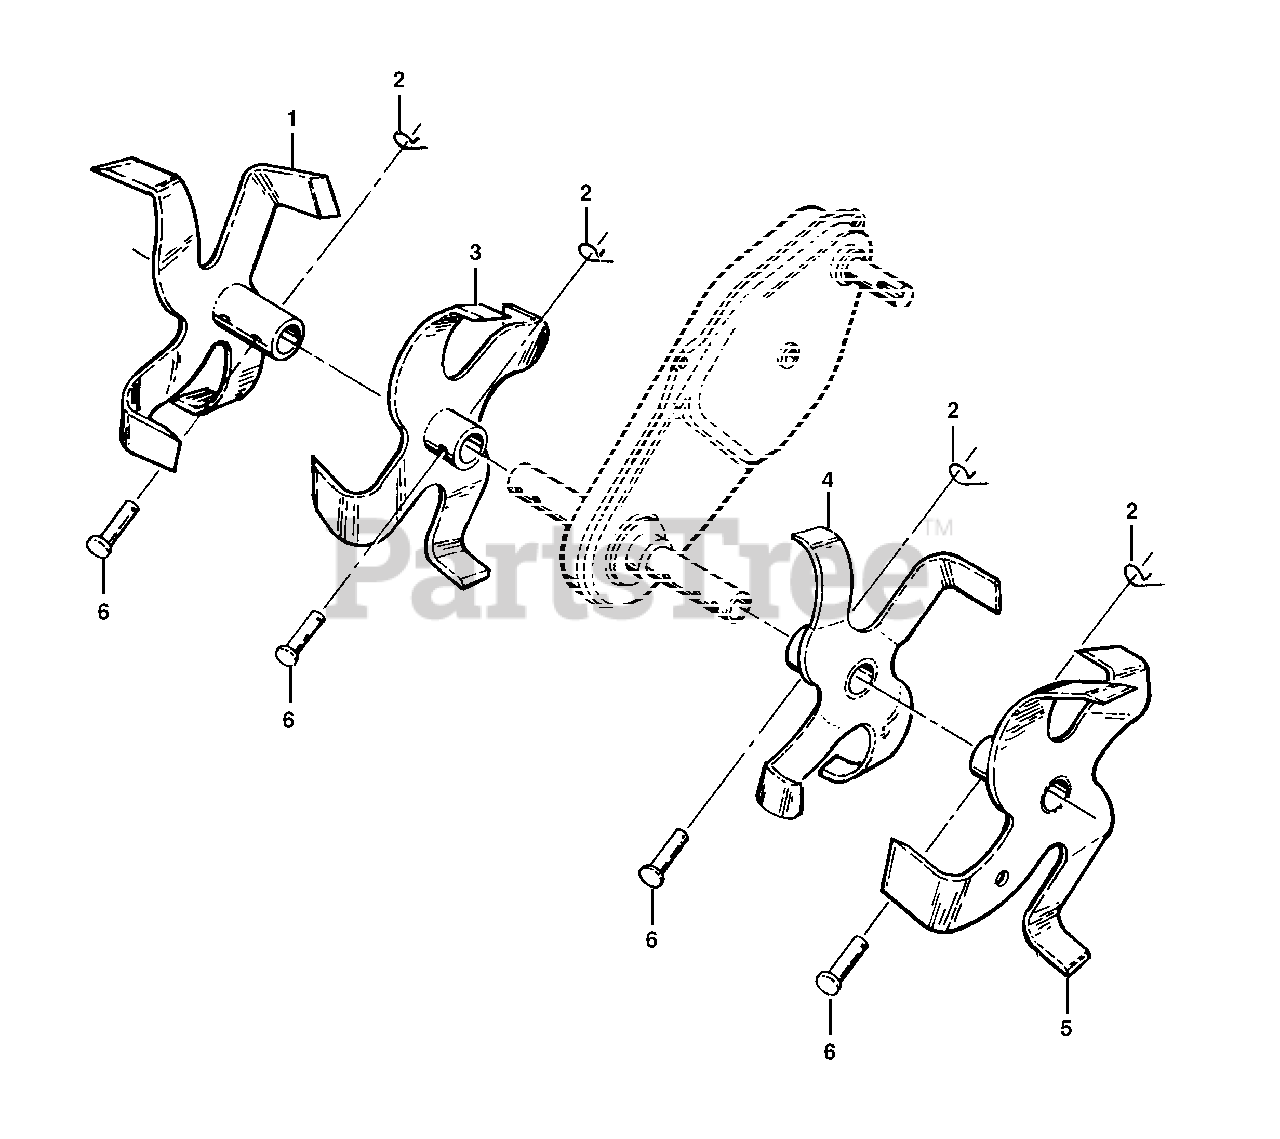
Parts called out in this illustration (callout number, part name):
1	Tine, Outer, R.H.
2	Retainer, Spring
3	Tine, Inner, R.H.
4	Tine, Inner, L.H.
5	Tine, Outer, L.H.
6	Pin, Clevis
